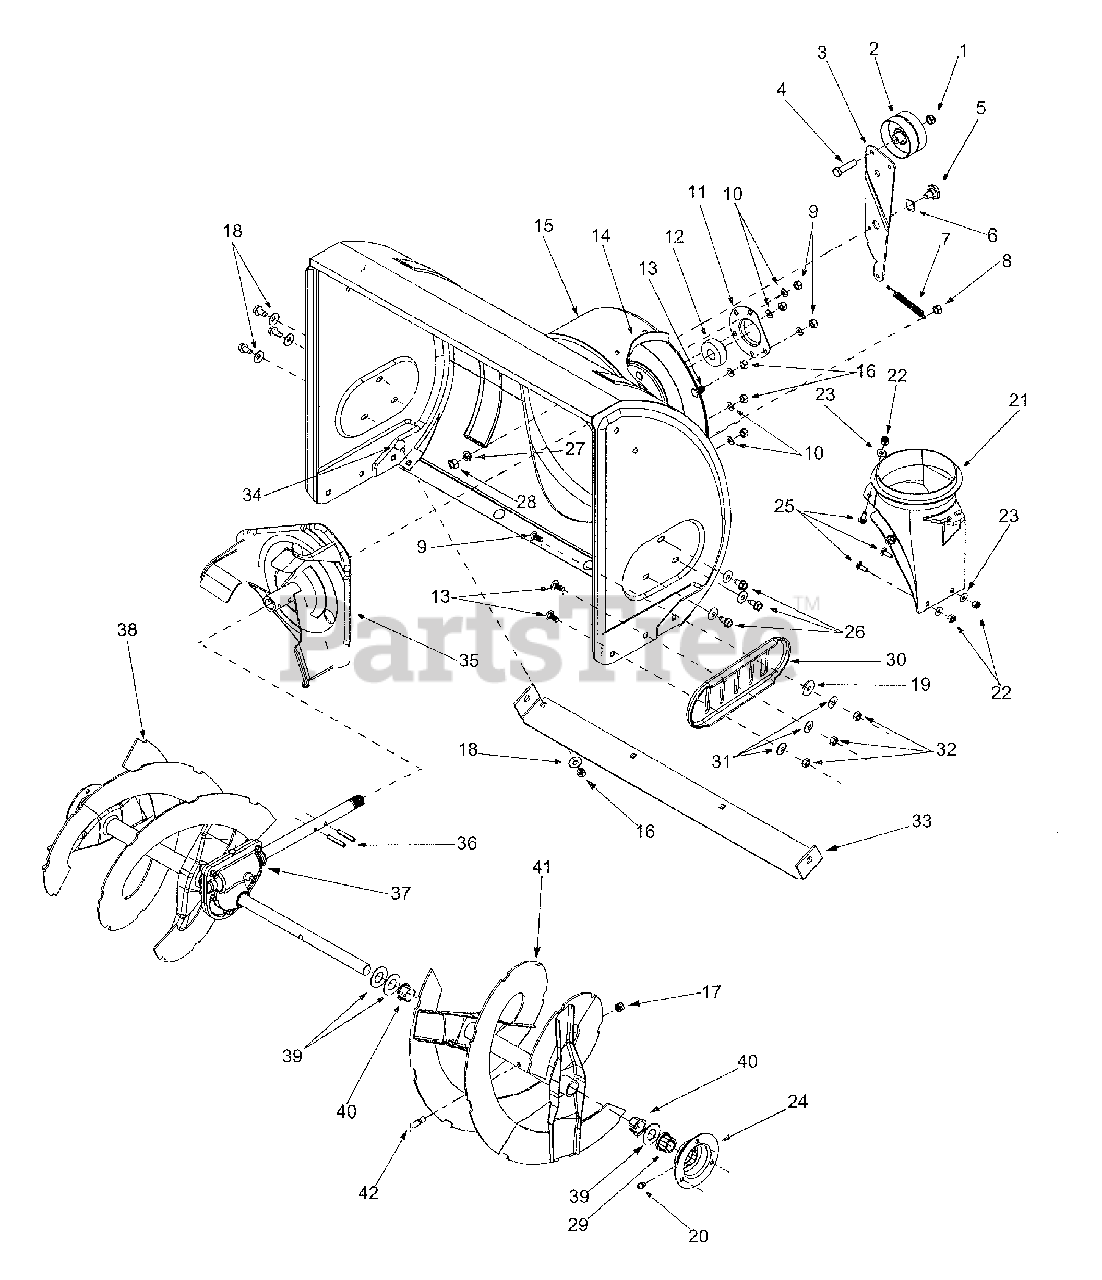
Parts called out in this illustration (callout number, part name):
1	Lock Jam Nut 3/8-24
4	Hex Cap Screw 3/8-24 x 1.50
5	Shoulder Screw
6	Flat Washer .656 ID x 1.25 OD
7	Extension Spring
8	Hex Nut 5/16-18
9	Carriage Bolt, 5/16 18 x 1.00
10	Lock Washer 5/16
12	Ball Bearing
13	Carriage Bolt, 5/16-18 x .75
17	Lock Nut 5/16-18
18	Belleville Washer
19	Flat Wshr, .344ID x 1.125 OD
20	Grease Fitting, 3/16" Drive
21	Chute Adapter
22	Hex Lock Nut 1/4-20
24	Bearing Housing w/Fitting
25	Carriage Screw 1/4-20 x .75
26	Hex Screw 5/16-18
27	Lock Washer 3/8
28	Hex Nut 3/8-16
29	Hex Flange Bearing
30	Skid Shoe
32	Hex Nut 5/16-18
34	Carriage Bolt 5/16-18 x 1.00
37	26" Gear Assy
40	Flange Bushing
777D04521	Label: Handle Panel
777120324	Label: Transport
777120820	Label: Panel LH
777120821	Label: Panel RH
777530511	Label: Chute Danger
777530514	Label: Housing Danger
